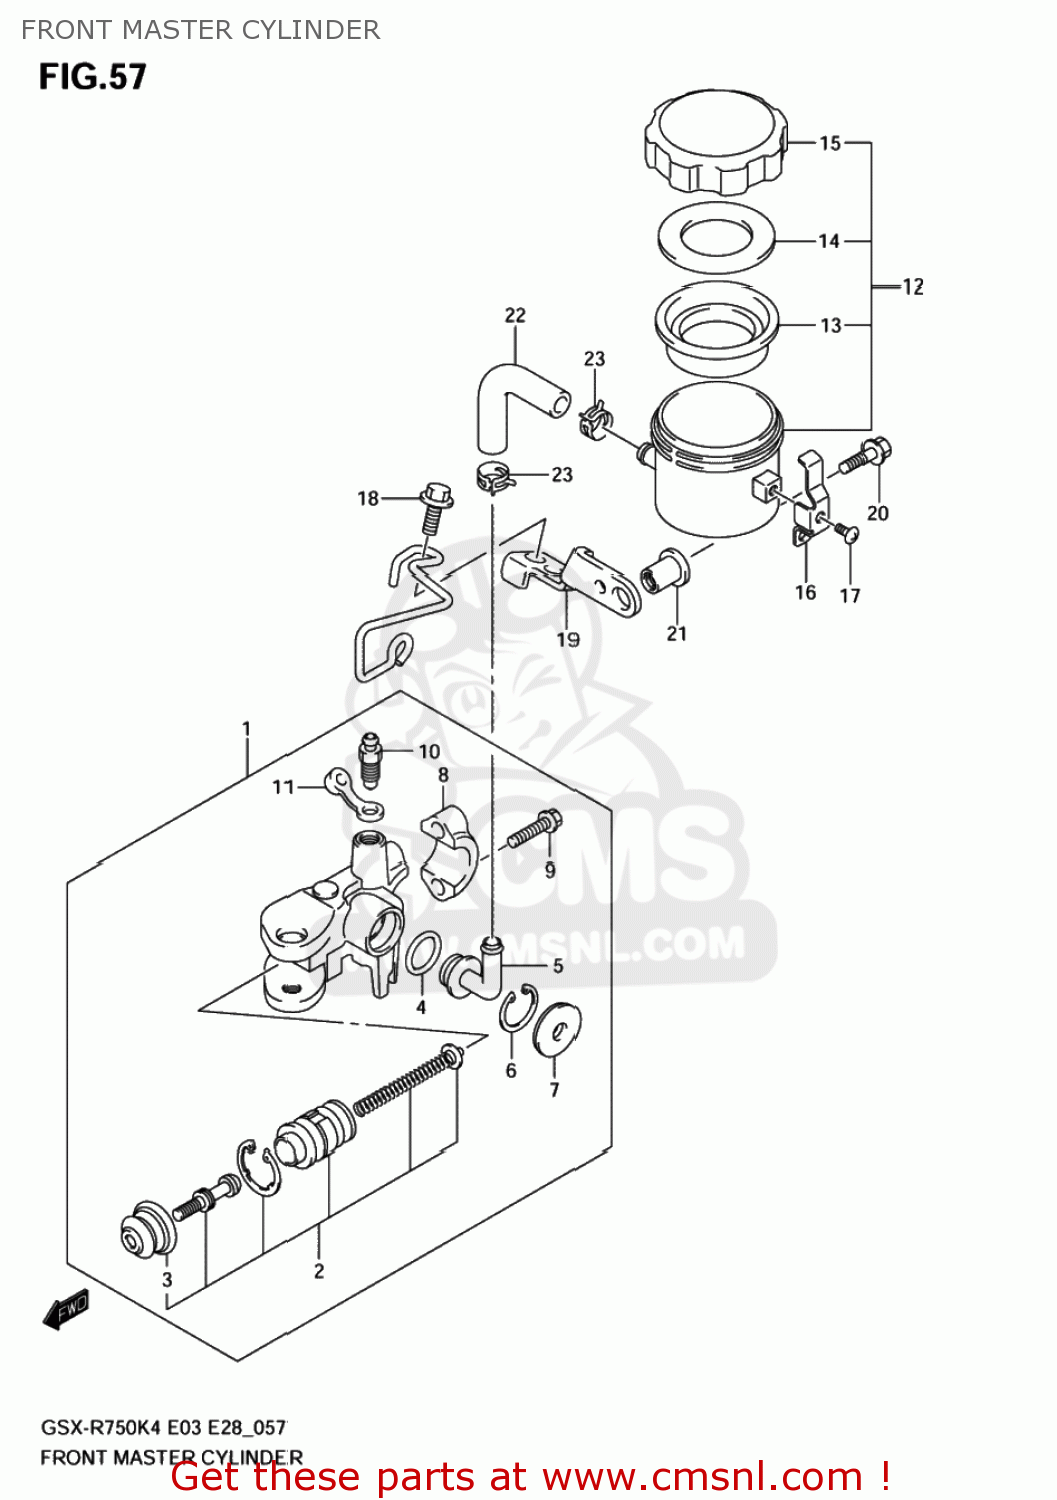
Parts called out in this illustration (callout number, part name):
1	CYLINDER ASSY,
2	PISTON/CUP SET
3	BOOT
4	O RING
5	CONNECTOR
6	CIRCLIP
7	COVER,DUST
8	HOLDER
9	BOLT(6X22)
10	BLEEDER
11	CAP,BLEEDER
12	TANK ASSY,RESERVOIR
13	DIAPHRAGM
14	PLATE,DIAPHRAGM
15	CAP
16	PLATE,RESERVOIR TANK CAP
17	SCREW
18	BOLT
19	BRACKET,FR RES
20	BOLT
21	NUT,COWLING SCREEN
22	HOSE,FR RESERVOIR TANK
23	CLAMP,RESERVOIR TANK FR
